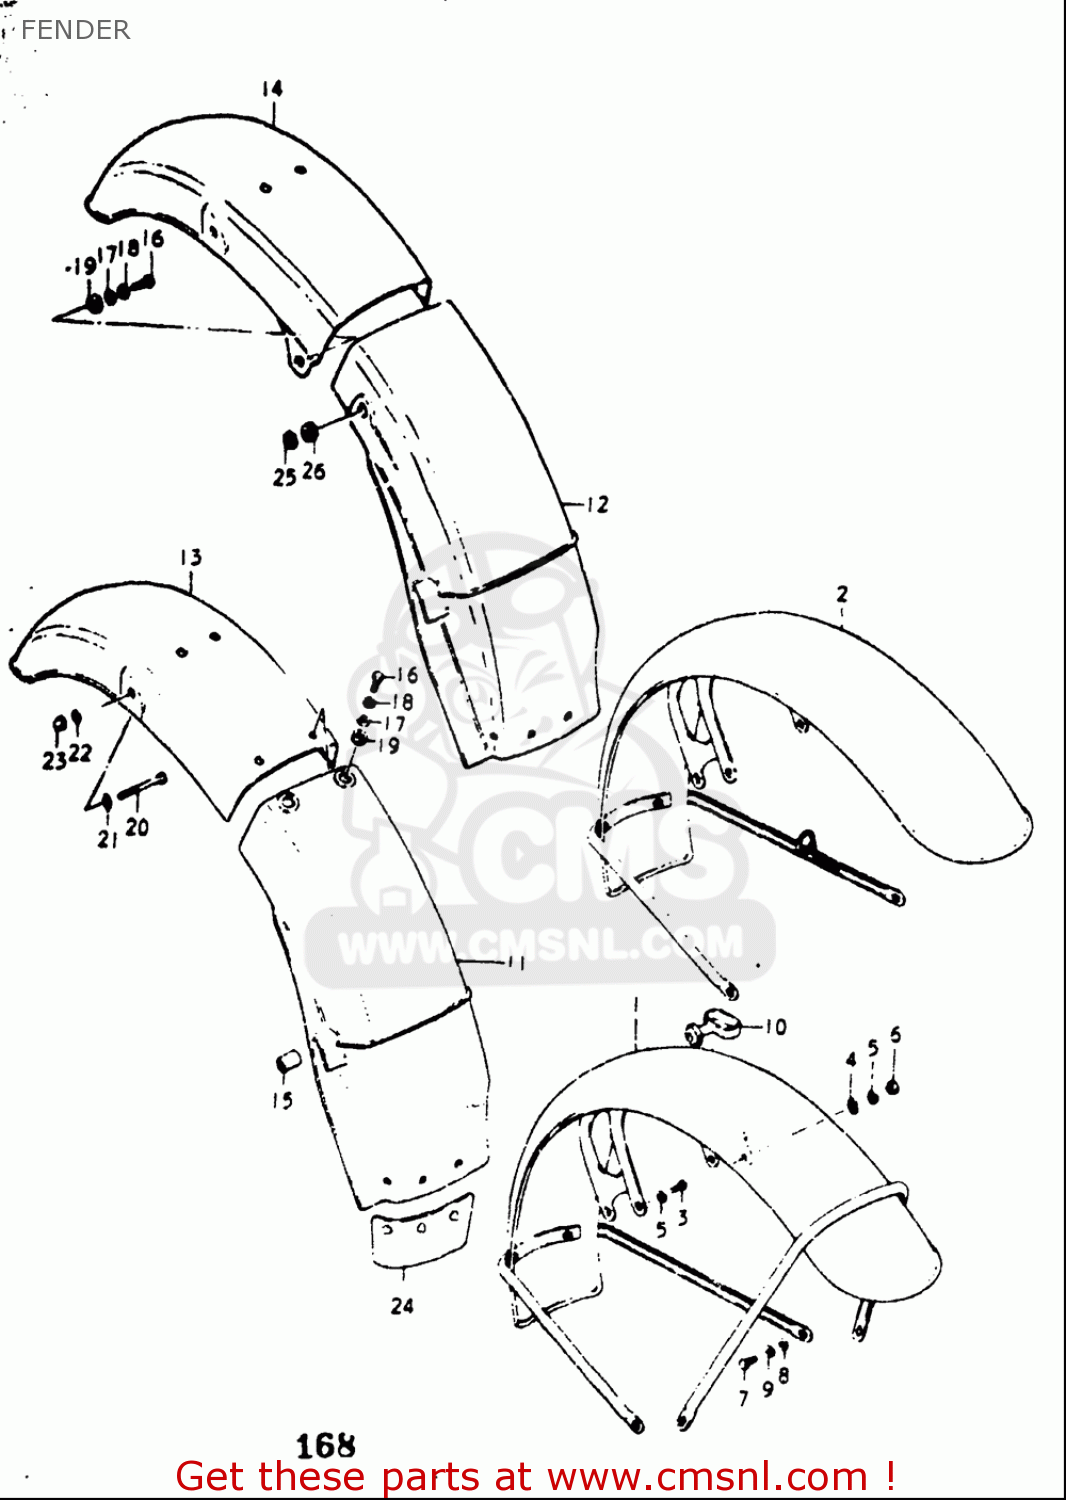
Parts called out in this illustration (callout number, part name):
1	FENDER ASSY,FR
2	FENDER ASSY,FR
3	BOLT
4	WASHER
5	WASHER,LOCK
6	NUT
7	BOLT
8	WASHER
9	WASHER,LOCK
10	GUIDE,CABLE
11	BODY,RR FENDER FR
12	BODY,RR FENDER FR
15	CUSHION
16	BOLT
17	WASHER
18	WASHER,LOCK
19	SPACER (6.5X20X5)
20	BOLT
21	WASHER
22	WASHER,LOCK
23	NUT
24	GUIDE,RR FENDER MUD
25	WASHER(6.5X18X1.6)
26	CUSHION
